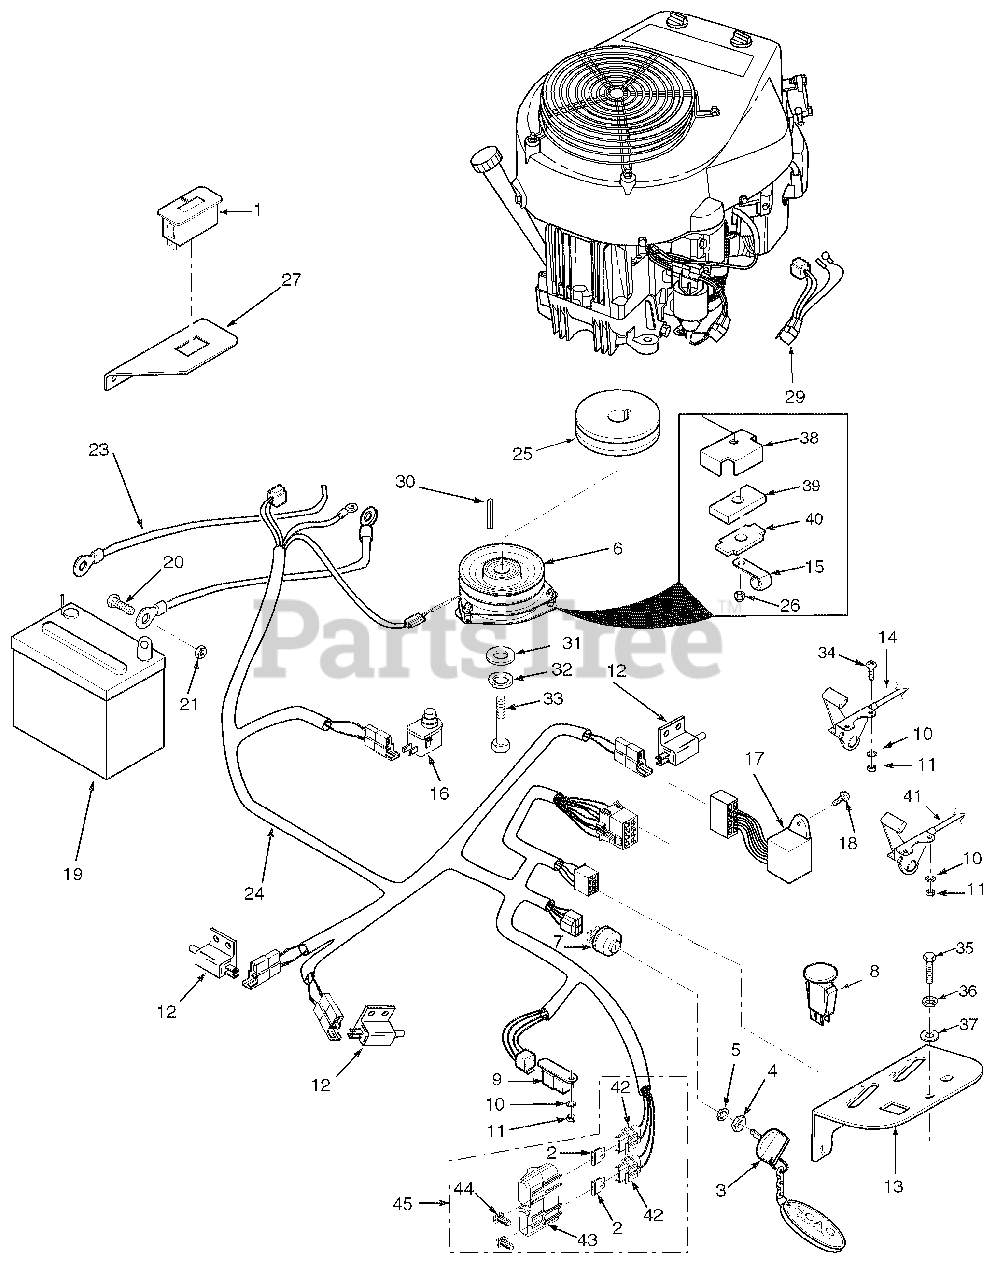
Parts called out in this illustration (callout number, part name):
1	Hourmeter
2	Fuse, 20 amp
3	Key, Ignition
4	Nut, Hex 5/8-32
5	Lockwasher, 5/8" Internal
6	Electric PTO Clutch GT3.5
7	Switch, Ignition
8	Switch, PTO
9	Relay
10	Lock Washer, #10 External Tooth
11	Nut, Hex #10-32
12	Switch, N/O
13	Panel, Instrument
14	Choke Control - Kohler
16	Switch, Seat
17	Module, Interlock
18	Screw, #10-32 x .5" Phillips Head
19	Battery
20	Bolt, Hex Head 1/4-20 x .5"
21	Nut, Hex 1/4-20
22	Cable, Battery Black
23	Cable, Battery Red
24	Wiring Harness, Main
25	Pulley, 5.45 OD x 1.125 Bore
26	Nut, Elastic Stop 5/16-18 Key
27	Mounting Bracket, Hour Meter
28	Screw, #10-32 x 1.5" Phillips Head
29	Adaptor, Wiring Harness
30	Key, 1/4 x 1/4 x 3-1/4"
31	Flatwasher, 7/16-.469 x 1-3/4" x 1/4"
32	Lockwasher, 7/16"
33	Bolt, Hex Head 7/16-20 x 2-1/4" UNF
34	Screw, #10-32 x 3/4"
35	Bolt, Hex Head 5/16-18 x 3/4"
36	Lockwasher, 5/16"
37	Flatwasher, 5/16-.375 x .875 x .083
38	Backing Plate
39	Rubber Pad, Clutch Stop
40	Plate, Backing
41	Throttle Control - Kohler & Kawasaki
42	Fuse Holder
43	Cover, Sealed Double
44	Clip, Wire
45	Doube Fuse Assembly, Sealed
